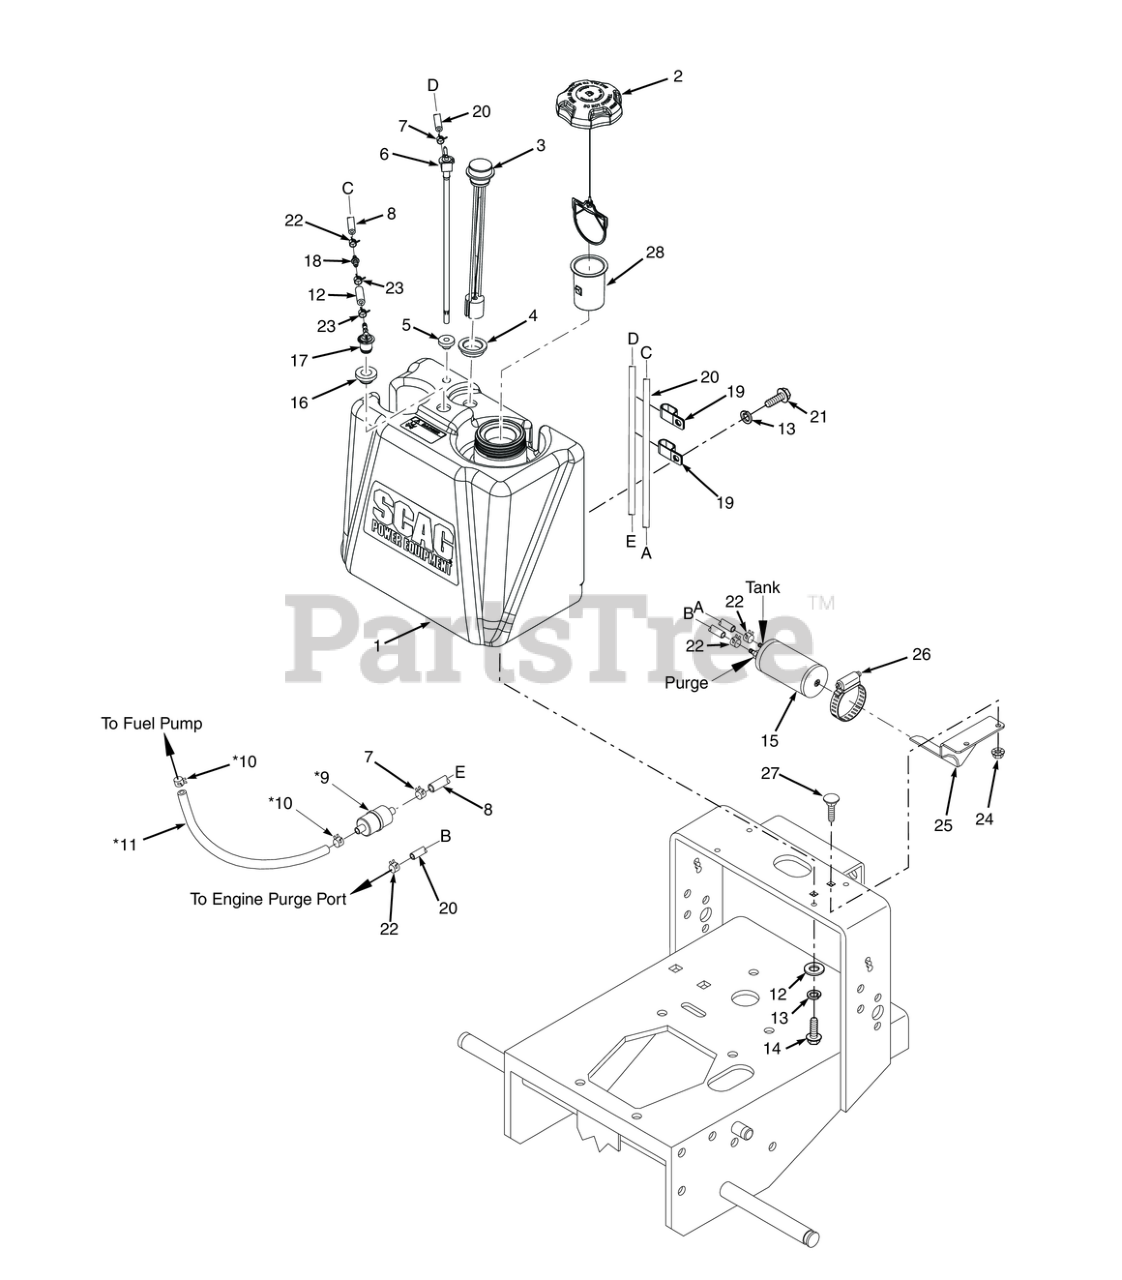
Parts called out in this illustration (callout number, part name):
1	Fuel Tank Assembly (incl. #3, 4, 5, 6, 16, 17)
2	Fuel Cap w/ Tether (E.P.A.)
2	Fuel Cap w/Tethered - California Models Only
3	Fuel Gauge Assembly
4	Grommet, Fuel Gauge
5	Bushing, 0.56" Dia. Viton
6	Valve, Fuel Shutoff w/Screen
7	Clamp, Fuel Hose 1/4" Hose I.D.
8	Fuel Hose, 1/4" I.D. Non-Perm (791DFI Fuel Return) - Order by Inch
9	Fuel Filter
10	Clamp, Fuel Hose
11	Fuel Hose
12	Hose, 1/4" Vapor Recovery (order by inch)
13	Lockwasher, 5/16 (.317 x .586 x .078) Helical Spring
14	Bolt, Heax Head 5/16-18 x 1" (48V / 52V)
15	Carbon Canister - SVR-36A / SVR-48V
16	Grommet, Viton,
17	Remote Vent, No Valve
18	Mender, 1/4 x 3/16 w/0.02 Hole
19	Clamp, Double Cable 5/8" ID.
20	Hose, Vapor Recovery 3/16" (order by inch)
21	BOLT, SERRATED FLANGE HEX HEAD 5/16-18 X 3/4"
22	Clamp, Vapor Recovery Hose 3/16"
23	CLAMP, FUEL HOSE(KAWASAKI ONLY)
24	Nut, Serrated Flange 5/16-18 (Right Front Engine Mounting, Briggs and Kohler Only)
25	Bracket, Canister Mounting
26	Clamp, 3-1/2" Max. Dia.
27	Bolt, Carriage 5/16-18x1" (large frame units only)
28	Tube, Fuel Tank Insert - 4"
